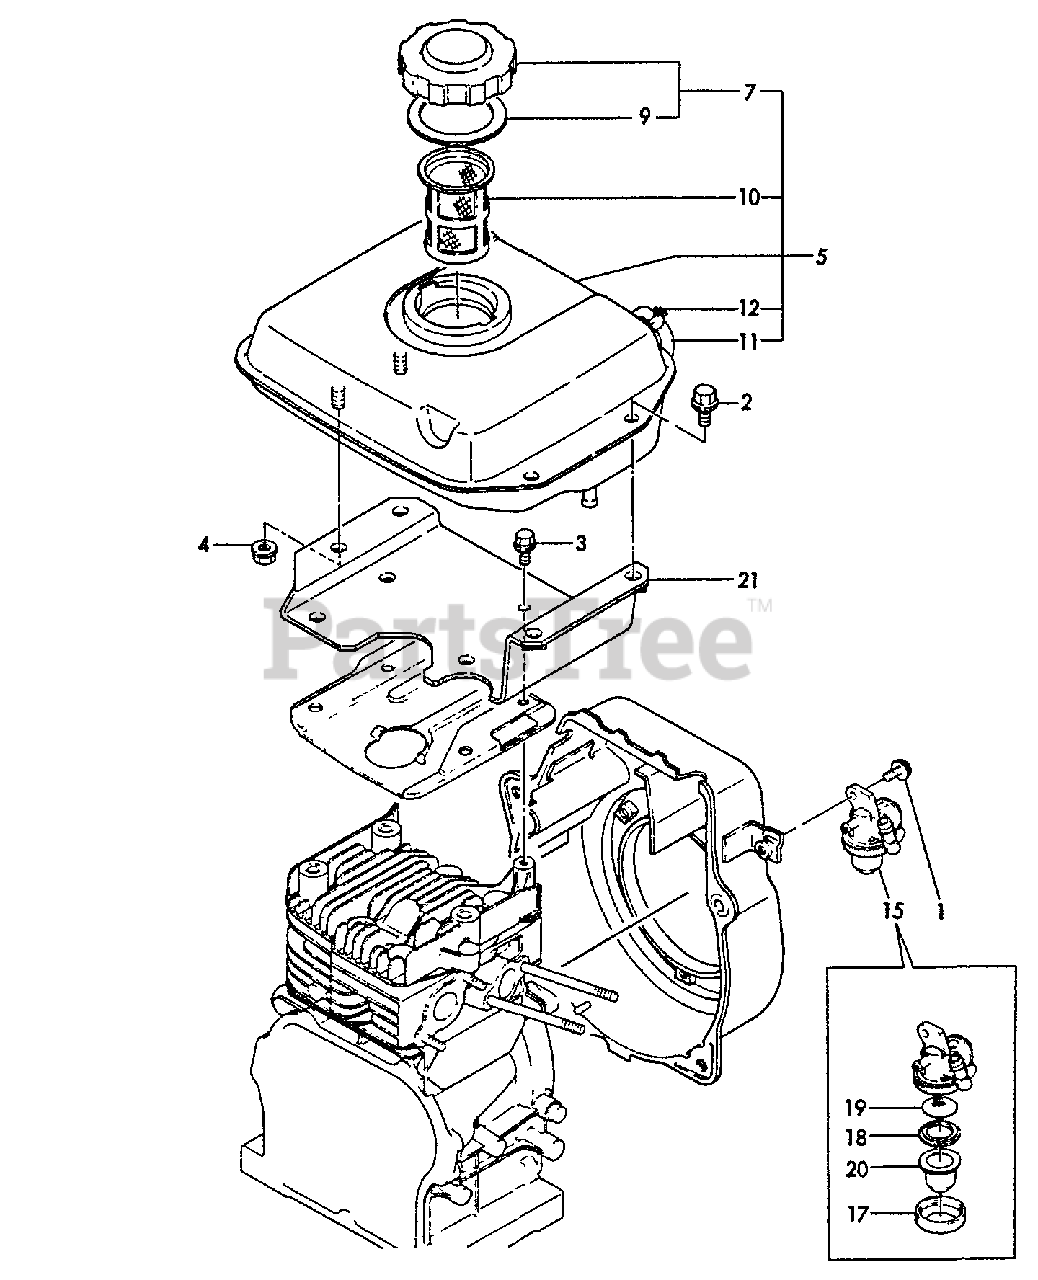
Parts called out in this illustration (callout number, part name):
1	BOLT - 6×12 -- PLATED
2	BOLT - 8×14 -- PLATED
3	BOLT - 6×8 -- PLATED
4	U-NUT M8
5	FUEL TANK ASSY
7	CAP ASSY
9	GASKET
10	STRAINER, FUEL
11	GAUGE, LEVEL
12	CLAMP, HOSE - 9
15	COCK ASSY, FUEL
17	RETAINER
18	GASKET
19	FILTER, FUEL
20	BOWL, STRAINER
21	BRACKET, FUEL TANK
